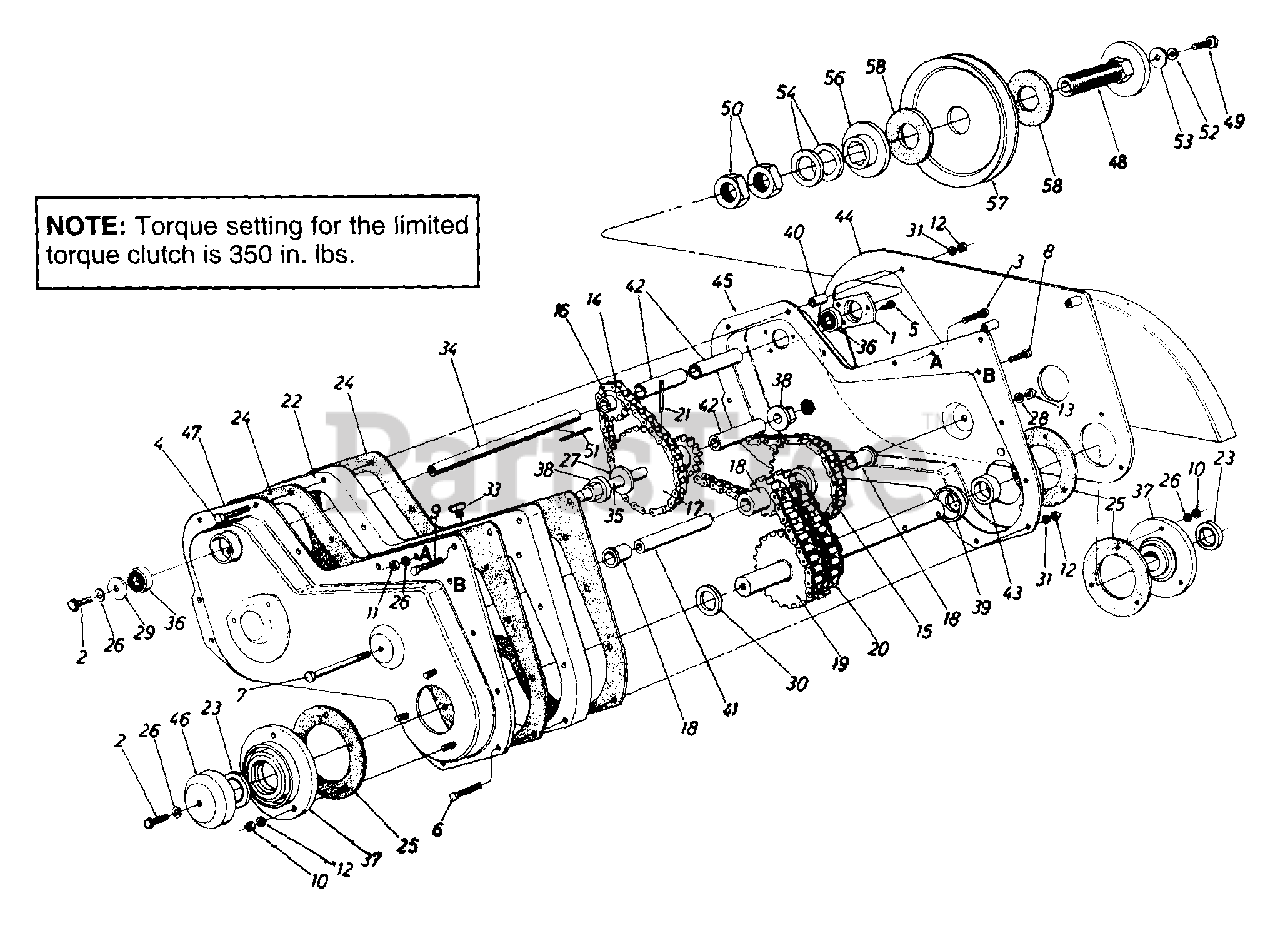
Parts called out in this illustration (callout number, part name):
1	Bearing Housing 1-3/8" Dia.
2	Hex Bolt 5/16-18 x .88" (Spec.)
3	Hex Bolt 5/16-18 x 1.5" Lg.
4	Hex Bolt 1/4-20 x 2.75" Lg.
5	Hex S-Tap Scr. 1/4-20 x .5" Lg.
6	Hex Bolt 1/4-20 x 1.5" Lg.
7	Hex Bolt 3/8-16 x 4.5" Lg.
8	Hex Scr. 1/4-20 x 1.5" Lg.
9	Hex TT-Tap Scr. 5/16-18 x 1.75"
10	Hex L-Nut 5/16-18 Thd.
11	Hex Nut 5/16-18 Thd.
12	Hex Nut 1/4-20 Thd."
13	Hex Nut 3/8-16 Thd.
14	#41 Chain 1/2" Pitch x 34 Links - Endless
15	#42 Chain 1/2" Pitch x 48 Links - Endless
16	Sprocket 10 Tooth .5" Pitch
17	10 & 28 Teeth Sprocket Ass'y.
18	8-2 & 28 Sprocket Sleeve Ass'y.
19	18-2 Sprocket Shaft Ass'y.
20	#50-2 Chain 5/8" Pitch x 28 Links - Endless
21	Spring Pin Spir. 1/4" Dia. x 1.5" Lg.
22	Spacer Block - Tiller Housing
23	Oil Seal 1-1/4" Dia.
24	Gasket for Tiller Housing
25	Gasket for Brg. Housing
26	L-Wash. 5/16" I.D.
27	Fl-Wash. .64" I.D. x 1.24" O.D.
28	L-Wash. 3/8" I.D.- H.D.
29	Fl-Wash. .344" I.D. x 1.125"
30	Special Washer
31	L-Wash. 1/4" I.D.
32	Grease
33	Vent Plug
34	Jack Shaft .525" I.D. x 7.78"
35	Sprocket Shaft .63" Dia. x 5"
36	Ball Brg. .62" I.D. x 1.38" O.D.
37	Bearing Housing - 1-1/4"
38	Hex Flange Brg.
39	Spacer 1.25" I.D. x 2.0" O.D.
40	Spacer .9" Lg.
41	Spacer 3.44" Lg.
42	Spacer .62" x .88" x 1.56" Lg.
43	Spacer .5" Lg.
46	Dust Cap
49	Hex Bolt 5/16-18 x 1.25" Lg. Grade 5
50	Hex Jam Nut 1.0-14 x 28 Thd.
51	Sq. Key 3/16 x 1.5" Lg.
52	L-Wash. 5/16" I.D.
53	Fl-Wash. .344" I.D. x 1.125"
54	Bell-Wash. 1.0" I.D. x 2.0"
56	Floating Disc 3-1/4" O.D.
57	5/8 V-Pulley 1.5" I.D. x 6.5"
58	Friction Pad 3-1/4" O.D. x 1-3/8" I.D.
